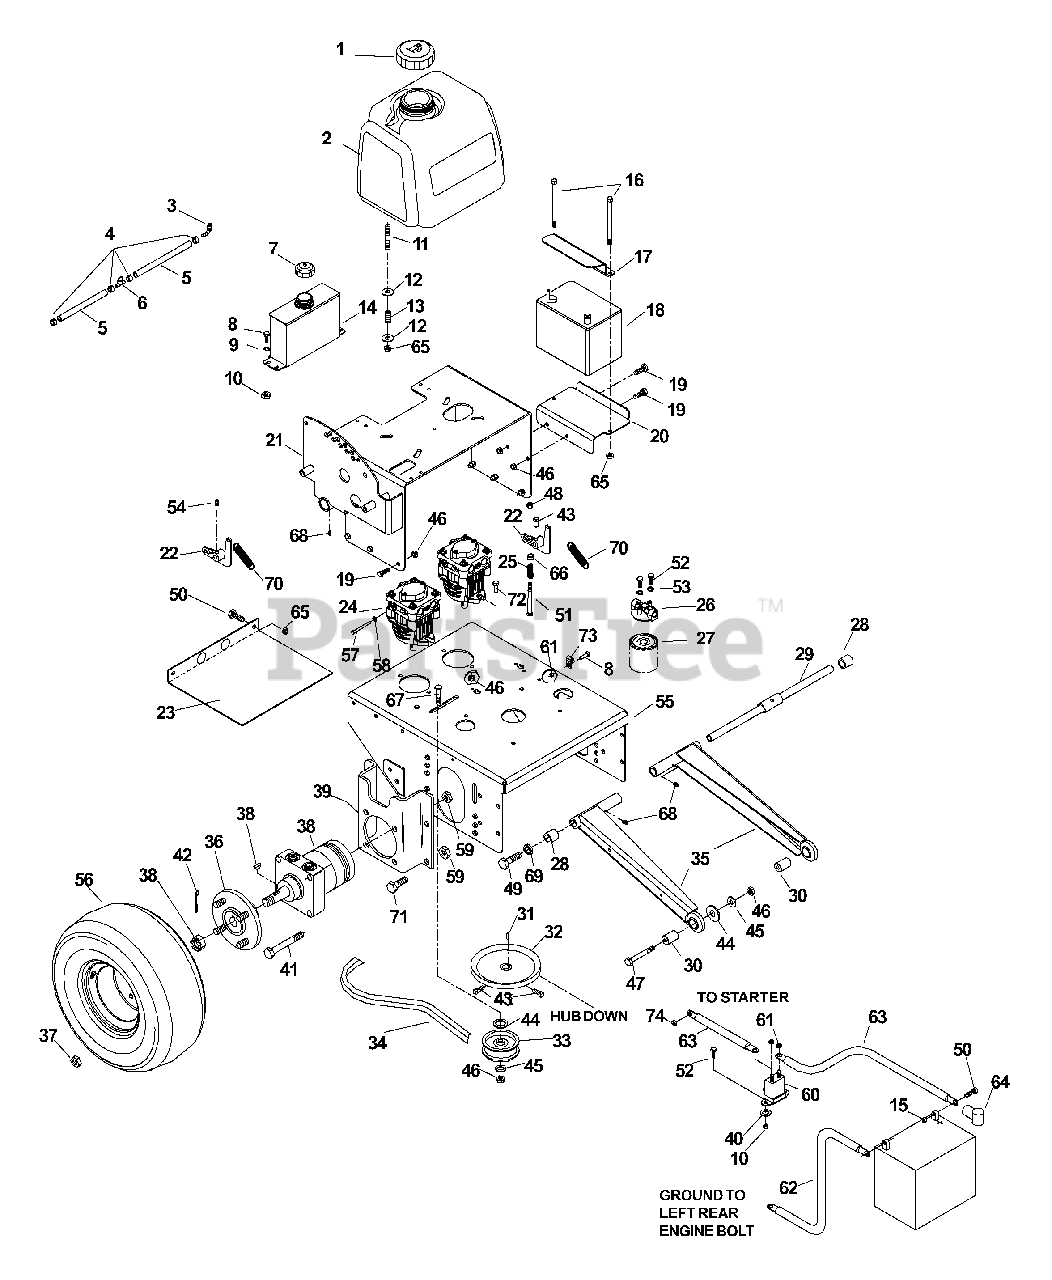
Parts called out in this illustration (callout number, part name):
1	FUEL CAP
3	FUEL FITTING
4	HOSE CLAMP
6	FUEL VALVE
8	HCS, 1/4C X 3/4
9	WASHER, 1/4
10	NUT, 1/4, CENTER LOCK
12	WASHER, 5/16
15	NUT, 5/16, CENTER LOCK
16	HCS, 5/16C X 7
17	BATTERY STRAP
18	BATTERY, DRY
19	HCS, 3/8C X 3/4
20	BATTERY TRAY
21	TANK SUPPORT
23	BELT SHIELD
24	PUMP W/POPPETS
26	FILTER HEAD
29	STRUT SHAFT
30	SPACER, FRONT
31	KEY, METRIC
33	IDLER PULLEY
38	HYD. MOTOR
39	MOTOR MOUNT
40	IT LOCKWASHER, 1/4
41	HCS 1/2C X 2 3/4
42	COTTER PIN
43	SET SCR. 5/16 X 5/8
44	WASHER, 1/2
45	WASHER, 3/8
46	NUT, 3/8, CENTER LOCK
47	HCS, 3/8C X 2 1/4
48	NUT, 3/8C, NYLOC
49	HCS, 1/2 X 1
50	HCS, 5/16C X 3/4
51	HCS, 3/8C X 2 3/4
52	HCS, 1/4C X 5/8
53	LOCKWASHER, 1/4
54	SET SCREW, 5/16-18 X 5/8
56	TIRE /WHEEL ASM.
56	RIM
57	CLEVIS PIN
59	NUT, 1/2C, NYLOC
61	NUT, 1/4, NYLOC
62	NEGATIVE CABLE
63	POSITIVE CABLE
65	NUT, 5/16C, NYLOC
67	RHSNB, 3/8C X 2
68	ZERK
69	LOCKWASHER, 1/2
70	SPRING, PUMP
71	HFCS, 1/2C X 1 1/4
72	HCS, 3/8C X 1
74	NUT, 1/4, THIN NYLOC
